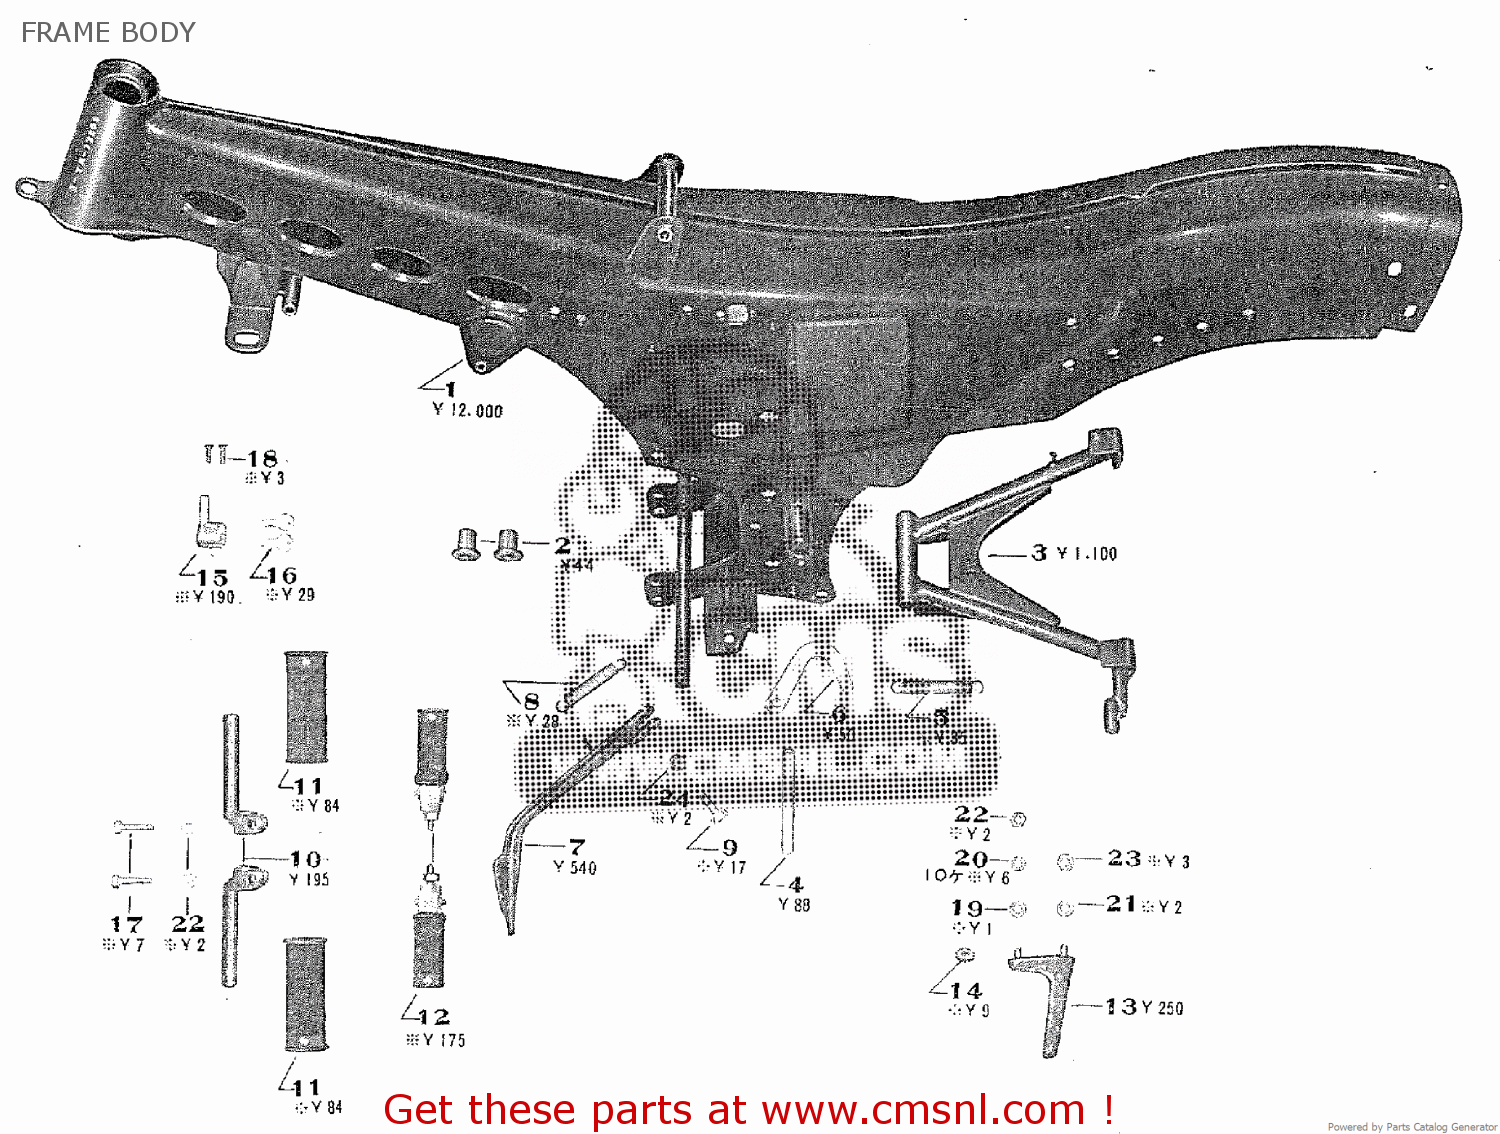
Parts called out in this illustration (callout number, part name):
1	FRAME COMP
2	SWING ARM BOSS BUSH
3	MAIN STAND COMP.
4	MAIN STAND SHAFT
5	MAIN STAND SPRING
6	MAIN STAND SPRING HOOK
7	SIDE STAND COMP.
8	SIDE STAND SPRING
9	SIDE STAND SET BOLT
10	FRONT STEP
11	FRONT STEP RUBBER
12	REAR STEP ASSY
13	STAND GRIP COMP.
14	DUST KEEP CAP
15	HEAD LOCK BODY
16	HEAD LOCK KEY
17	8X35 HEXAGON BOLT
18	5X20 CROSS SCREW
19	8MM PLANE WASHER
20	8MM SPRING WASHER
21	10MM SPRING WASHER
22	8MM HEXAGON NUT
23	10MM HEXAGON NUT
24	10MM HEXAGON NUT
